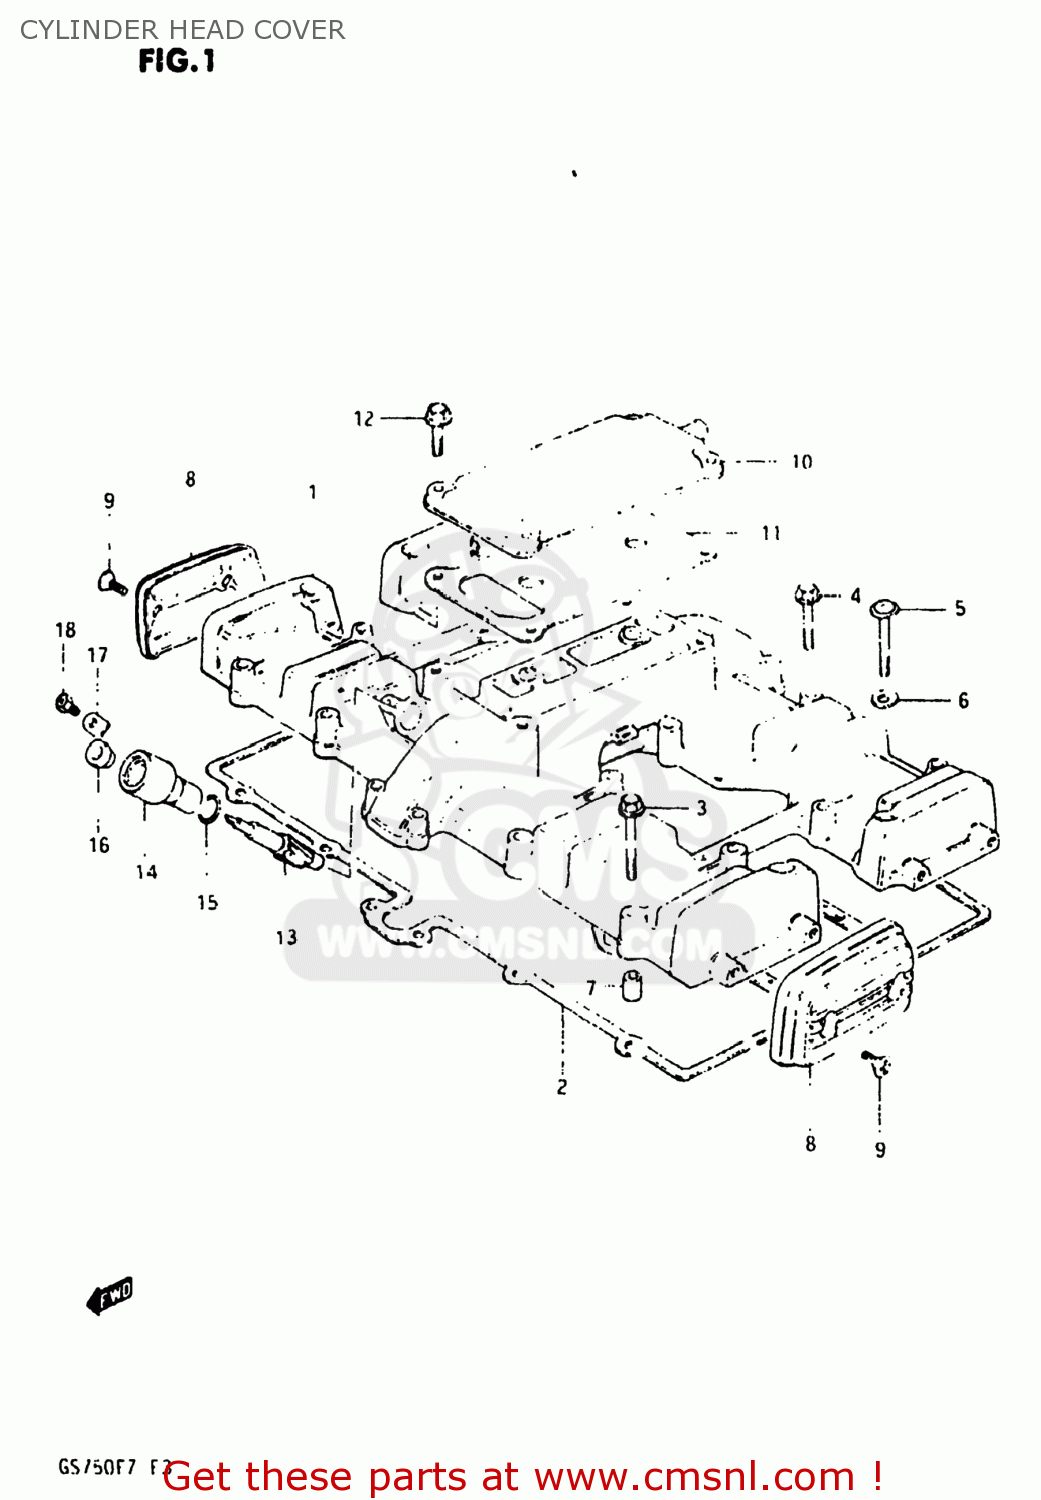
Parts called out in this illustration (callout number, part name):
1	COVER,CYLINDER HEAD
2	GASKET,CYLINDER HEAD COVER (MCA)
3	BOLT
4	BOLT 6X35
5	SCREW 6X40
6	GASKET (NAS)
7	PIN(6.2X8X11)
8	CAP,CYLINDER HEAD COVER
9	SCREW(5X12)
10	COVER,BREATHER
11	GASKET (MCA)
12	BOLT,REAR
13	GEAR,TACHOMETER DRIVEN
14	SLEEVE,TACHOMETER DRIVE
15	SEAL,TACHOMETER DRIVEN
16	SEAL,OIL(5X12X8)
17	PLATE,TACH DRIVE GEAR SLEEVE
18	SCREW(5X12)
